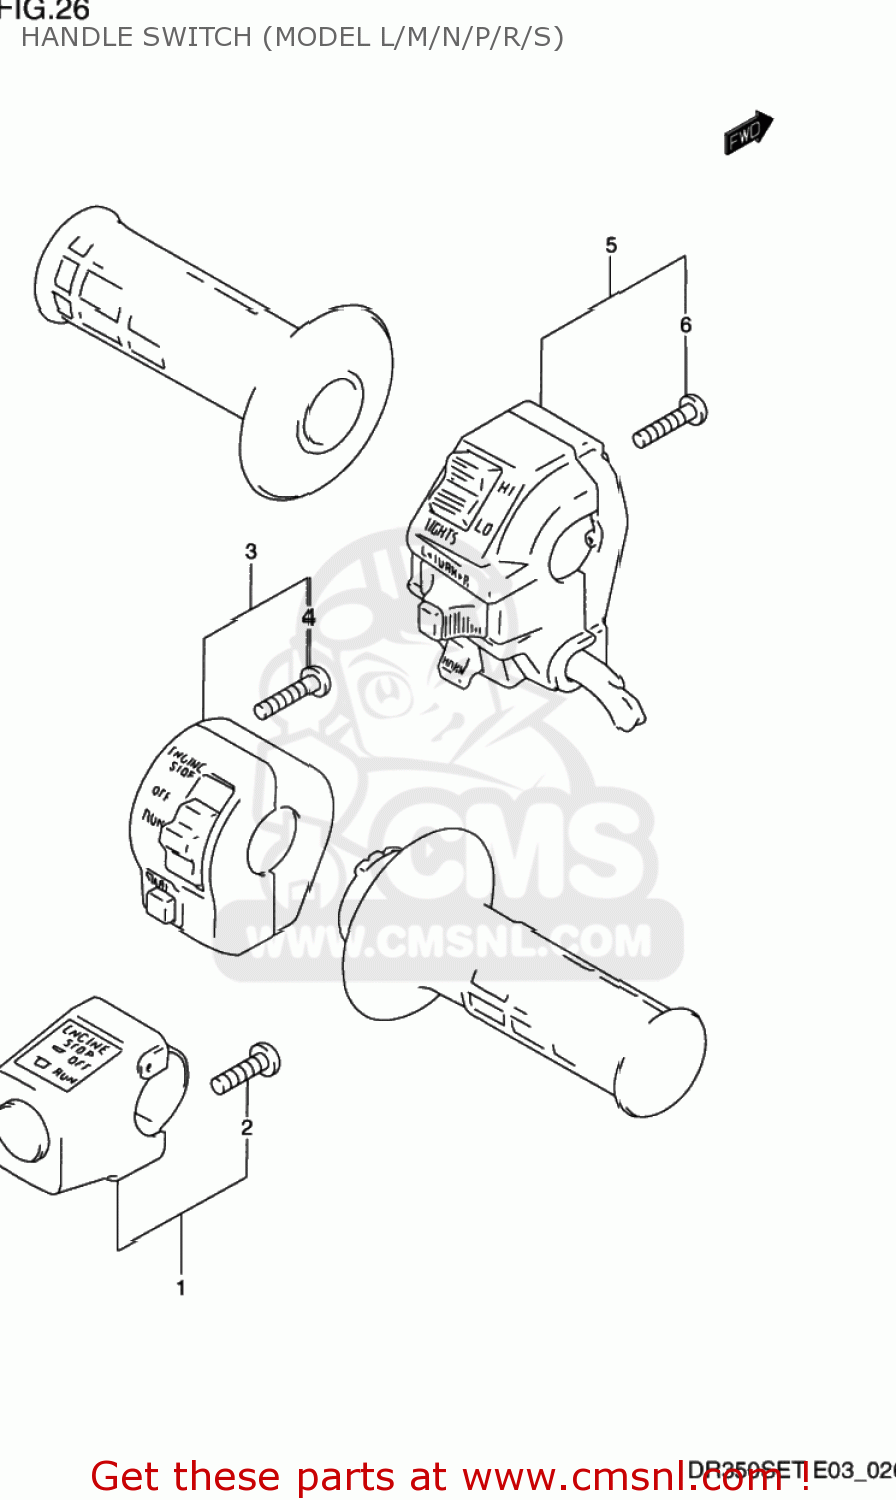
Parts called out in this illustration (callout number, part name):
1	SWITCH ASSEMBLY,HANDLE,RIGHT
2	SCREW
3	SWITCH ASSEMBLY,HANDLE,RIGHT
4	SCREW
5	SWITCH ASSEMBLY,HANDLE,LEFT
6	SCREW
